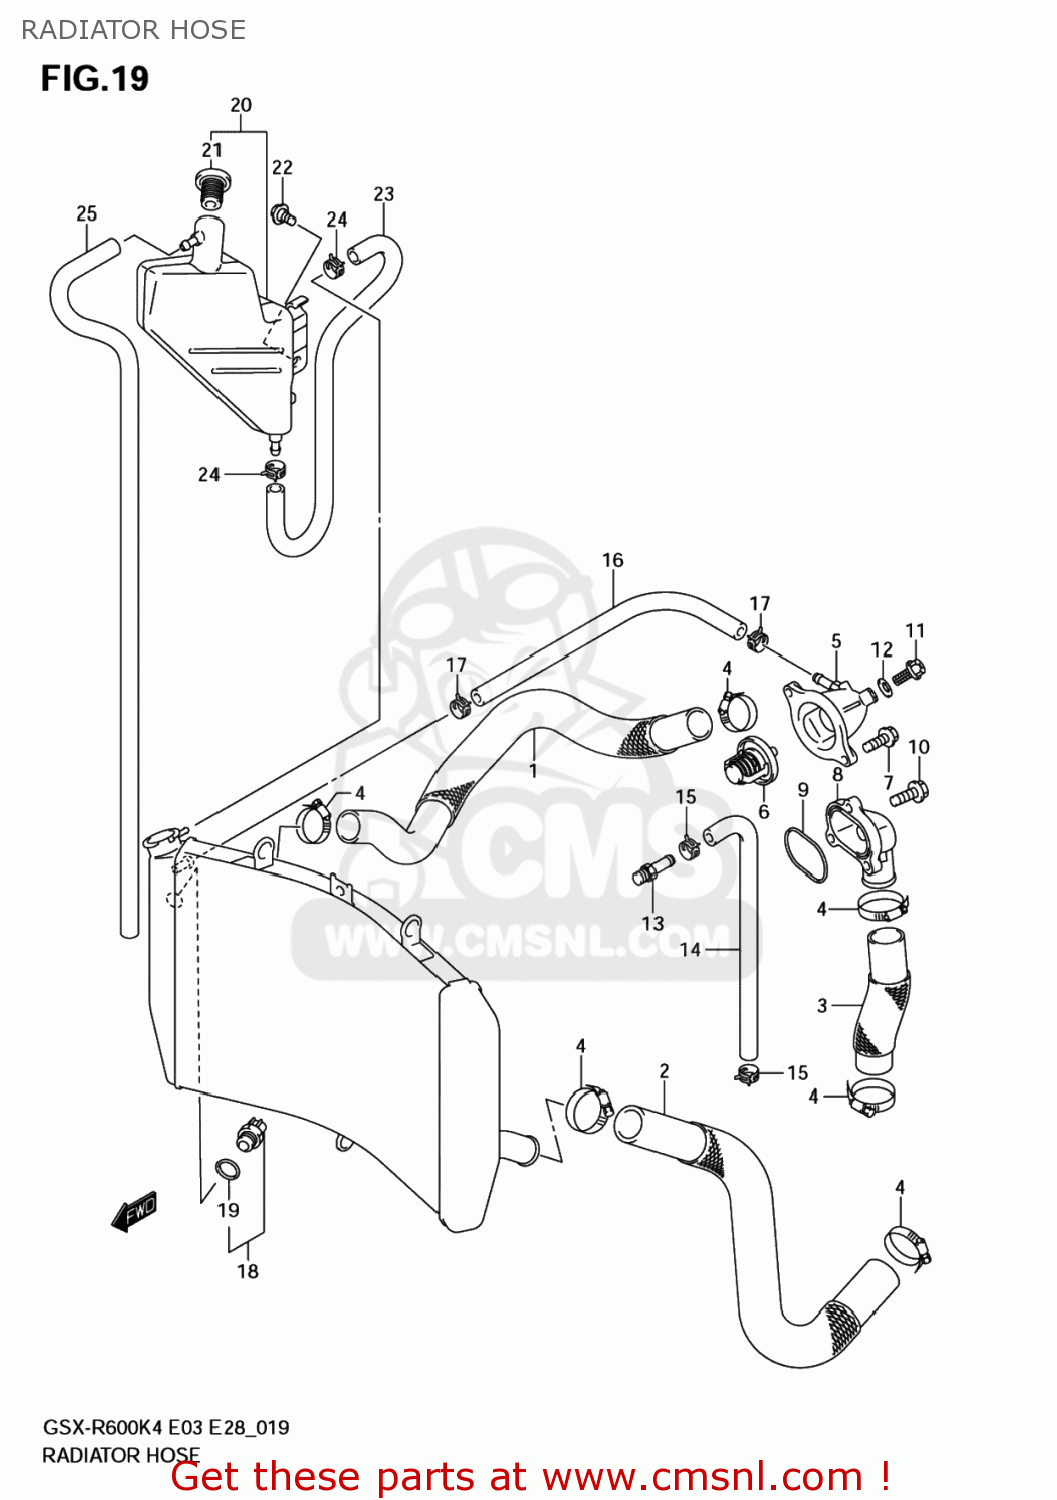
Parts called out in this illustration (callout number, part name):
1	HOSE,RADIATOR INLET
2	HOSE,RADIATOR OUTLET
3	HOSE,CYLINDER INLET
4	CLAMP
5	COVER,THERMOSTAT
6	THERMOSTAT,WATER 88 DEG
7	SCREW
8	CONNECTOR,CYL.
9	O RING,CYL WATER CONNECTOR
10	SCREW
11	UNION BOLT,AIR VENT
12	GASKET(6.4X11.5X0.8) (NAS)
13	BOLT UNION
14	HOSE,WATER BYPASS
15	CLAMP
16	HOSE(5X11X600)
17	CLIP
18	SWITCH,RADIATOR FAN
19	O-RING
20	TANK ASSY,RESERVOIR
21	CAP,RESERVOIR TANK
22	BOLT(6X12)
23	HOSE,RESERVOIR TANK INLET
24	CLIP
25	HOSE,RESERVOIR
